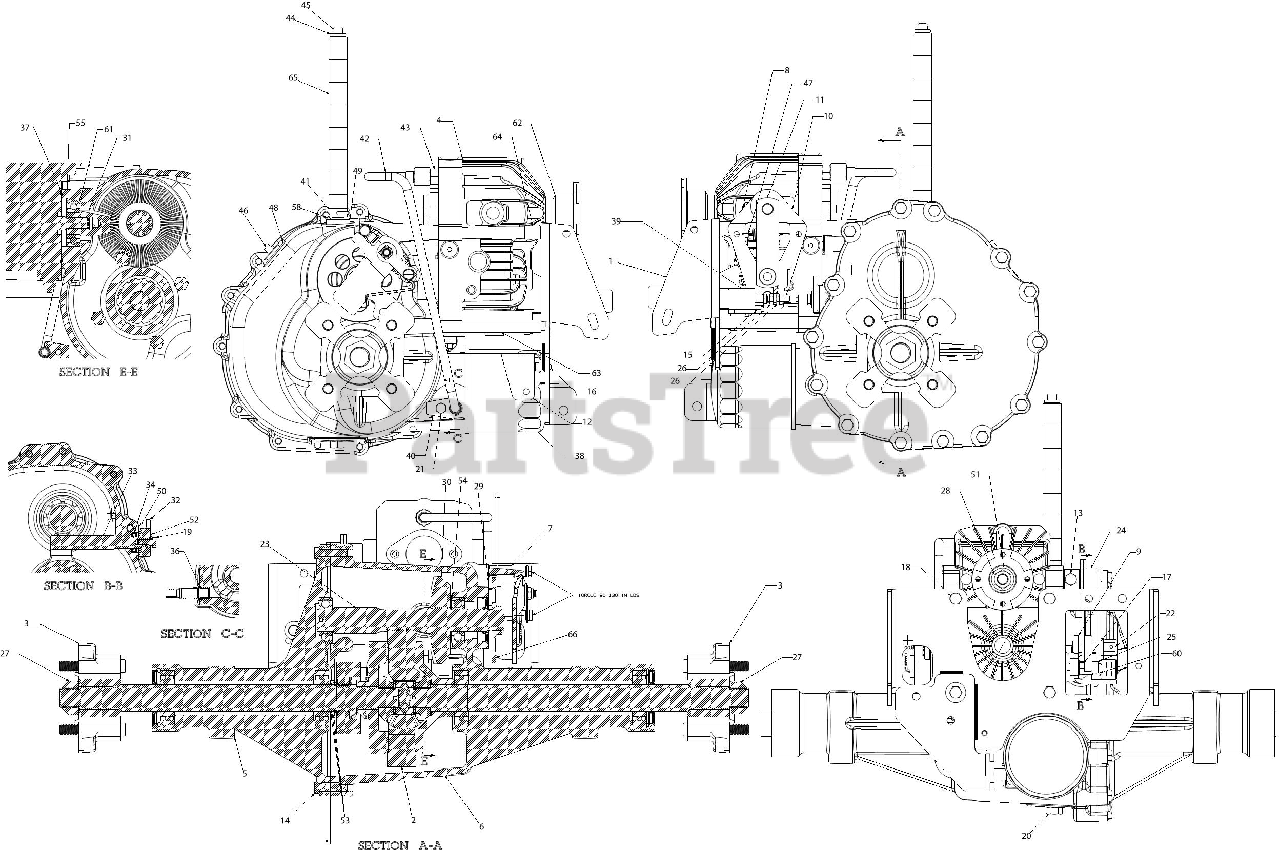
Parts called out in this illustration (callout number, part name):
1	TORQUE BRACKET ASSEMBLY
2	DIFFERENTIAL ASSEMBLY
3	WHEEL HUB ASSEMBLY
4	HYDRO PUMP
5	TRANSMISSION HOUSING (LH)
6	TRANSMISSION HOUSING (RH)
7	BRACKET ASSEMBLY (RH)
8	NEUTRAL ARM (LH)
9	NEUTRAL RETURN ARM
10	NEUTRAL ARM (RH)
11	NEUTRAL CONTROL ARM
12	DUMP VALVE PLATE
13	BOLT 5/16-24 x .625 GR2
14	SCREW 5/16-18 x 1.25 GR5
15	SCREW 1/4-20 X1.00 GR5
16	SCREW 1/4-20 X.500
17	SCREW 5/16-18 x .500
18	SCREW 5/16-18 x 5.19 GR5
19	SCREW 1/4-20 x .620 GR5
20	SCREW M14X1.5X.827
21	SCREW 1/4-20X.75 GR5
22	NEUTRAL CONTROL WELD PIN
23	OUTPUT SHAFT 9T
24	ADAPTOR HUB
25	WELD PIN
29	BRAKE PUCK
30	BEVEL GEAR 54T
31	BEVEL GEAR
32	DIFF LOC ACTUATE ARM
33	DIFF LOC ACTUATOR YOKE
34	OIL SEAL .5000 x .8750 x .2500
36	O-RING .426X.566X.070
37	GLAND SEAL
38	HYDRAULIC FILTER
39	INTERLOCK SWITCH (NO/NC)
40	TUBE CLAMP
41	FUEL HOSE CLAMP
42	HYDRO PICKUP TUBE
43	SWIVEL CONNECTOR
44	PLASTIC VENT
46	SHIPPING PART
47	EXTENSION SPRING
48	RUBBER GROMMET
49	VENT FITTING GROMMET
50	WASHER .51 x 1.5 x .07
51	BELL WASHER
52	SPRING WASHER BELL
53	FLAT WASHER 1.187X1.56X.062
54	THRUST WASHER
55	SPRING WASHER
58	VENT TUBE FITTING
60	SHOULDER SCREW
61	PTO SHAFT BALL BEARING
62	PUMP ADAPTER SPLINED
63	HYDRO SPACER .364 x .540 x 3.51
64	SPACER-HYDRO .323X.600 x .740
65	FUEL LINE 1/2" ID
66	BRAKE-DISC 43TEETH
